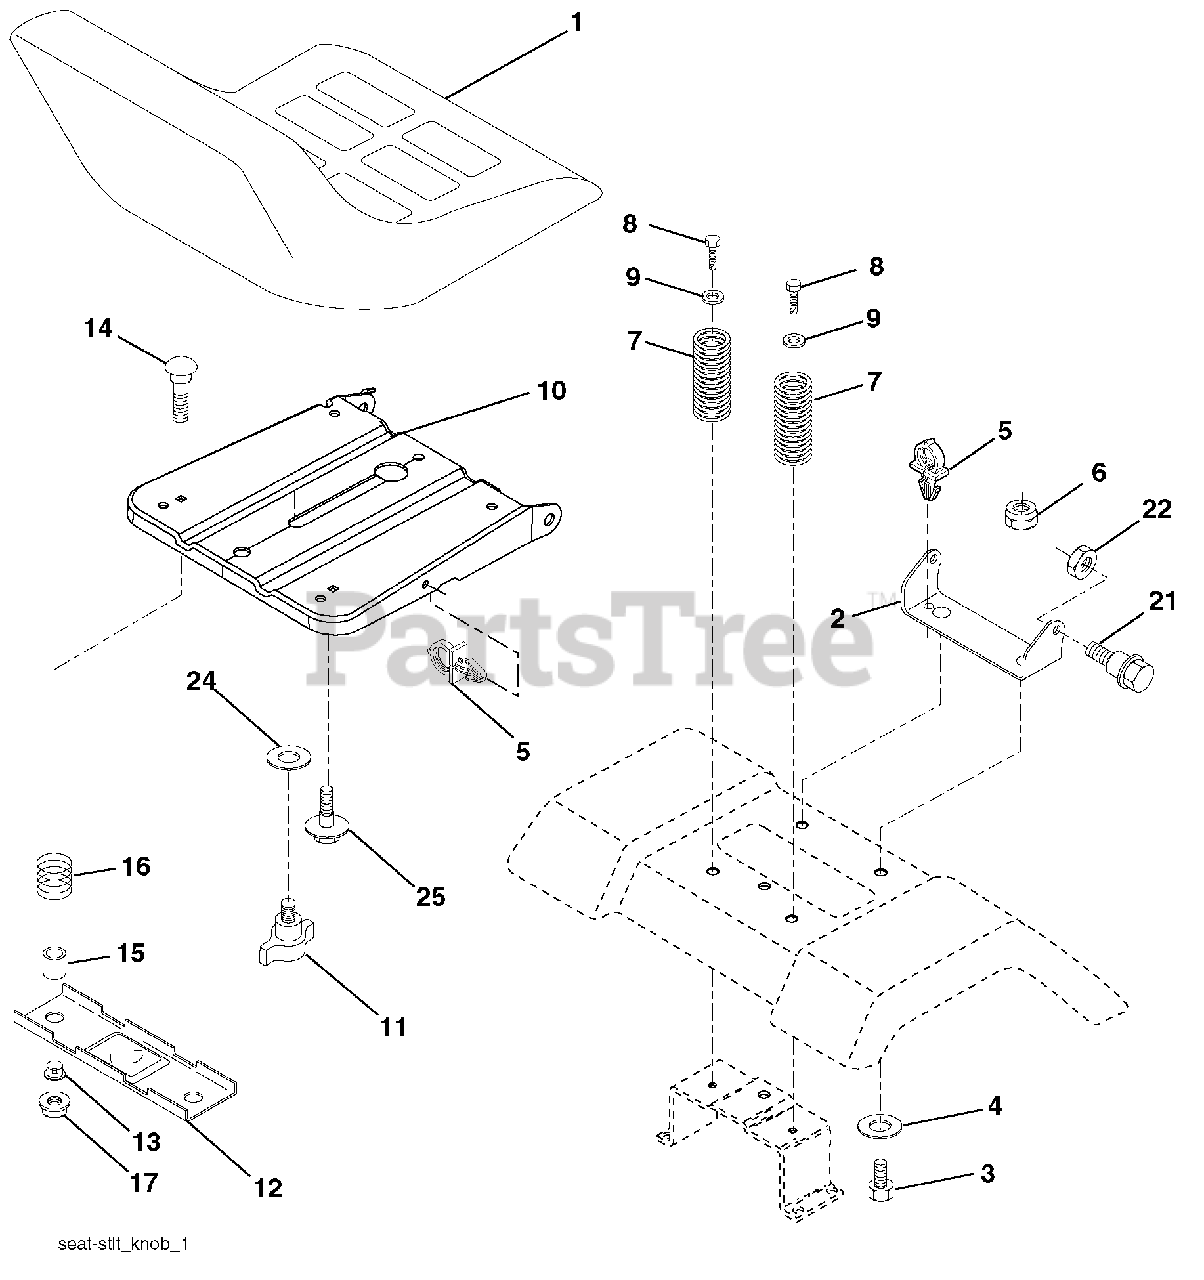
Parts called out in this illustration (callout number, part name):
1	Seat
2	Bracket Seat Pivot
3	Bolt Hex 3/8 - 16 x 1
4	Washer 13/32 x 1 x10 Ga.
5	Clip Push-In Hinged
6	Nut Lock Hex w/Ins 3/8 - 16
7	Spring Seat Cprsn 2 250 Blk Zi
8	Screw 3/8-16 x 1.5
9	Washer 13/32 x 1 x 14 Ga.
10	Pan Pnt Seat
11	Knob Seat
12	Bracket Pnt Mounting Switch
13	Bushing Snap Blk Nyl
14	Bolt Rdhd Sht Nk 1/4 - 20 x 1 -1/2
15	Spacer Split .28 x .96
16	Spring Cprsn
17	Nut Lock 1/4 Lge Flg
21	Bolt Shoulder 5/16-18 unc-2A
22	Nut Lock Hex w/Ins 5/16 - 18
24	Washer 17/32 x 1-3/16 x 12 Ga.
25	Bolt Shoulder 5/16-18 x .62
